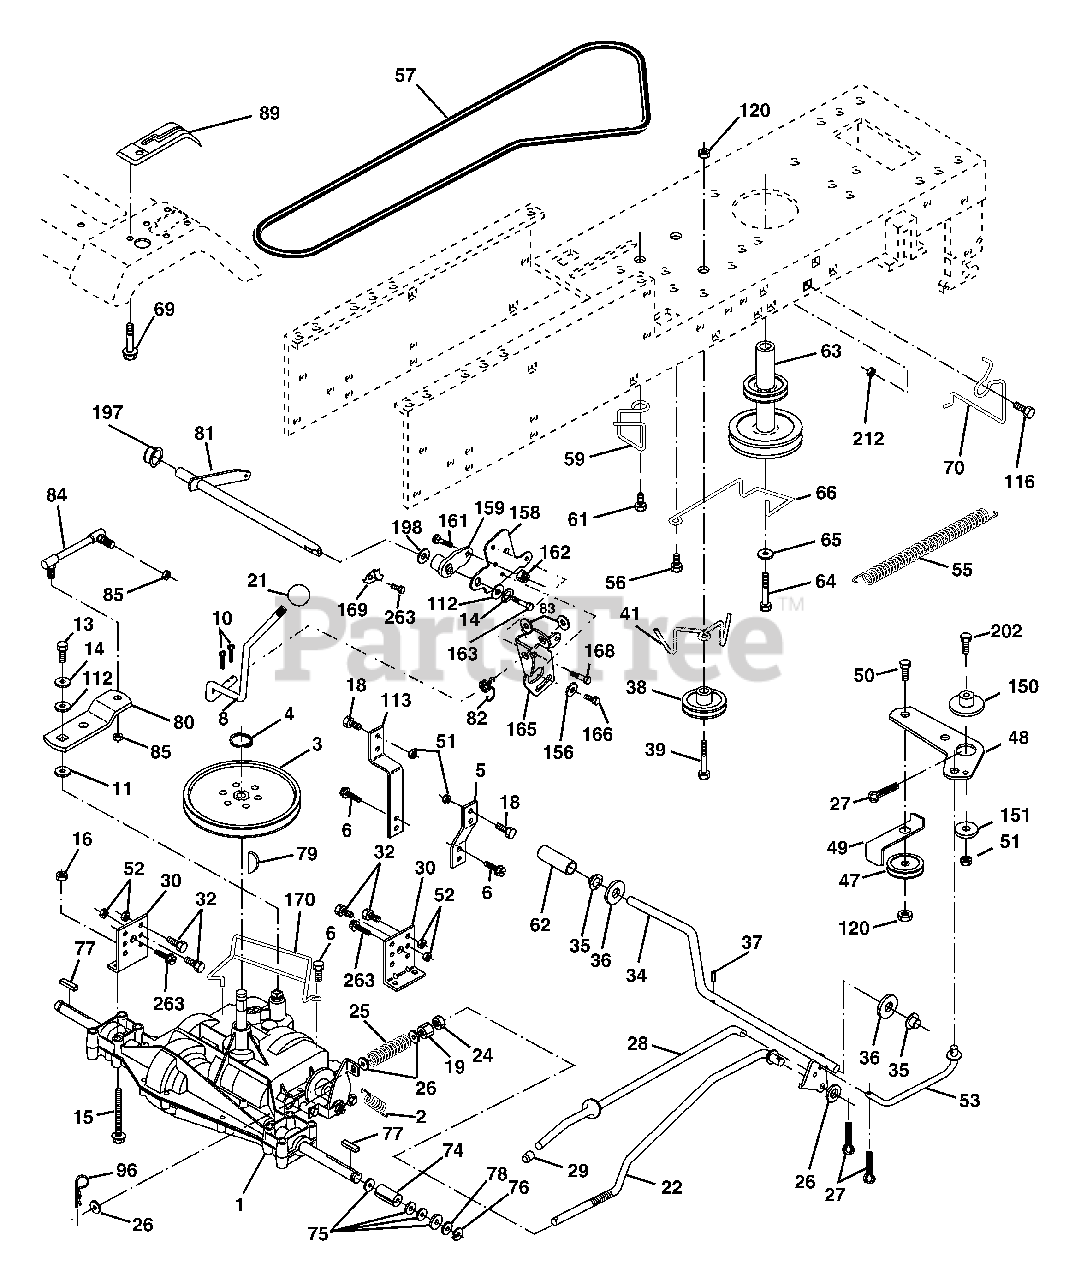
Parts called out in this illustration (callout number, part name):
2	Spring Return Brake
3	Pulley Transaxle 18" tires
4	Ring Retainer # 5100-62
5	Strap Torque 30 Degrees RH
6	Screw 5/16-18 x 3/4
8	Rod Shifter Blk
10	Pin Cotter 1/8 x 1 Cad
11	Washer Plate Shf 388 Sq Hole
13	Bolt 1/4-28 unf Gr. 8 w/Patch
14	Washer Lock Hvy Helical 1/4
15	Bolt Hex Flghd 5/16-18 Gr. 5
16	Nut 5/16-18
18	Bolt Fin Hex 3/8-16 unc x 1 Gr. 5
19	Nut lock Hex w/Ins 3/8-16 Unc
21	Knob Rd 1/2-13 Plstc Thds Blk
22	Rod Brake LT
24	Nut Hex Jam 3/8-16 unc
25	Spring Rod Brake 2 00 Zinc
26	Washer 13/32 x 13/16 x 16 Ga.
27	Pin Cotter 1/8 x 3/4 Cad
28	Rod Brake Parking LT/YT
29	Cap Brake Parking Black
30	Bracket Transmission
32	Bolt Fin Hex 5/16-18 x 3/4
34	Shaft Asm Pedal Foot Nibbed
35	Bearing Nylon Blk 629 Id
36	Washer 21/32 x 1 x 16 Ga.
37	Pin Roll 3/16 x 1"
38	Pulley Composite Flat
39	Bolt 3/8-16 x 2-3/4
41	Keeper Belt Idler
47	Pulley Idler V Groove Plastic
48	Bellcrank Clutch Grnd Drv STL
49	Retainer Belt Style Spring
50	Bolt Carr Sh 3/8-16 x 1-1/2 Gr. 5
51	Nut Crownlock 3/8-16 unc
52	Nut Crownlock 5/16-18 unc
53	Link Clutch 7 66
55	Spring Return Clutch 6 75
56	Screw 3/8-16 x 1-1/4
57	V-Belt Ground Drive 95
59	Keeper Belt Chassis Span Ctr
61	Screw 3/8-16 x .875
62	Cover Pedal Blk Round
63	Engine Pulley LT/YT
64	Bolt Hex 7/16-20 x 4 Gr. 5
65	Washer Lock Hvy Hlcl Spr 7/16
66	Keeper Belt Engine
69	Screw 1/4 x 1/2 unc
70	Guide Belt Mower Drive RH
74	Spacer Axle
75	Washer 25/32 x 1 1/4 x 16 Ga.
76	E-ring #5133-75
77	Key Square 2 0 x 1845/ 1865
78	Washer 25/32 x 1-5/8 x 16 Ga.
79	Key Woodruff
80	Arm Shift Transaxle
81	Shaft Asm Cross Taper
82	Spring Torsion Shift
83	Washer 17/32 x 3/4 x 16 Ga.
84	Link Transaxle
85	Nut Lock Center 1/4-28
89	Console Shift
96	Retainer Spring 1"
112	Washer 9/32 x 3/4 x 10 Ga.
113	Strap Torque 90 Degrees LH
116	Bolt Rdhd Sq Neck 3/8-16 x 1
120	Nut Lock Flg 3/8-16
150	Spacer Retainer Lt
151	Washer 13/32 x 2 x 10 Ga.
156	Washer Srrrtd 5/16 ID x 1.0 x .125
158	Bracket Shift Mount
159	Hub Shift
161	Bolt 1/4-20 x 3/4 Gr. 5
162	Nut Crownlock 1/4-20 unc
163	Bolt Hex Fin 1/4-20 unc x 1 Gr. 5
165	Bracket Pivot Lever
166	Screw 5/16-18 x 5/8
168	Bolt Shoulder 5/16-18 x .561
169	Plate Fastening
170	Keeper, Belt Transaxle
197	Nyliner Snap-In 5/8
198	Washer Nylon
202	Bolt Carr Sh 3/8-16 x 1-3/4 Gr. 5
212	Nut Hex Flg Lock
263	Screw 3/8-16 x 3/4
